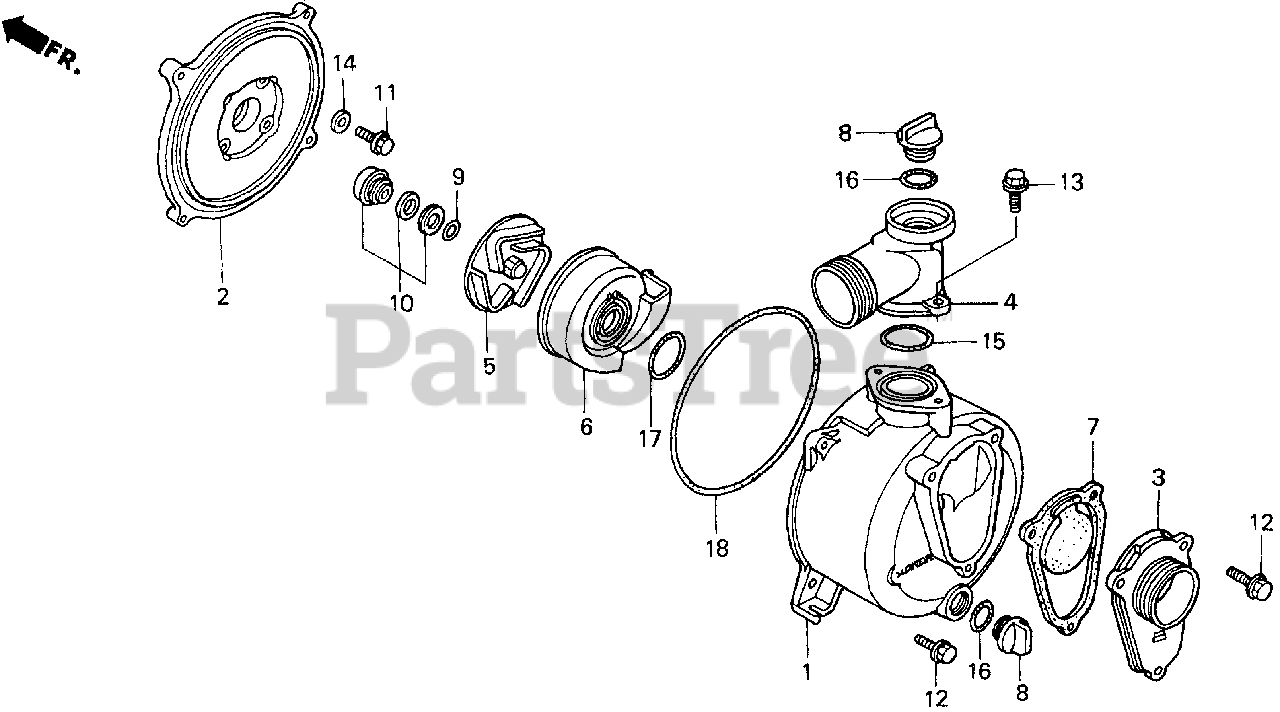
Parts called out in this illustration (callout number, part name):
2	COVER, CASING
3	PIPE, INLET
4	PIPE, OUTLET
6	CASE, VOLUTE
7	VALVE, IN.
8	CAP, FILLER
9	SHIM A, ADJUSTER (0.3) (STD)
9	SHIM B, ADJUSTER (OS) (0.5)
10	SEAL ASSY., MECHANICAL
11	BOLT, FLANGE (8X28)
12	BOLT, FLANGE (8X25)
13	BOLT, FLANGE (8X20)
14	WASHER (8MM)
15	O-RING (54X3.5)
16	O-RING (24X3.5)
17	O-RING (57X5.7)
18	O-RING (196X3.5)
